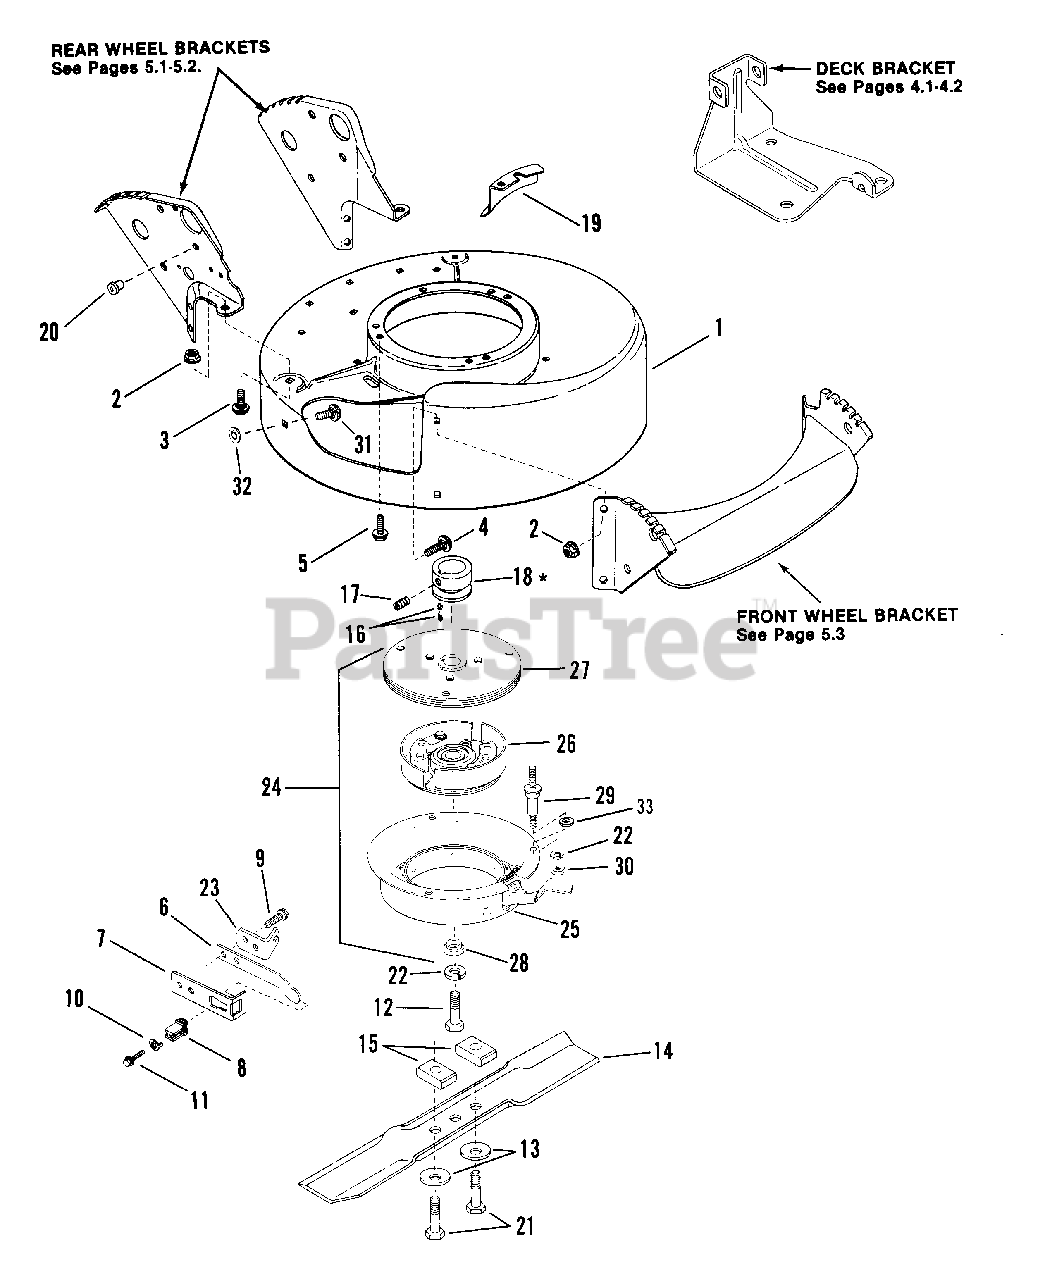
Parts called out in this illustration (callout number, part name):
1	DECK, Mower
2	NUT, Hex Flanged Lock
3	BOLT, 5/16-18 x 1/2" Short Neck Carriage Gr. 5
4	BOLT, 5/16-18 x 1" Short Neck Carriage
5	SCREW, 3/8-16 x 1" Hex Head Self-tapping (Engine Mounting)
6	SPRING, Wheel Bracket Type Interlock
7	BRACKET, Wheel Bracket Type Interlock
8	INSULATOR, Interlock
9	SCREW, 1/4-20 x 1/2" Hex Self-tapping
10	WASHER, No. 8 TAB Int. Tooth Lock
11	SCREW, No. 8-18 x 3/4" Hex Head Machine
12	SCREW, 3/8-24 x 2.0" Hex Head Cap
13	WASHER, Cone
14	BLADE, Cutter
15	SPACER, Blade
16	KEY, Hi-Pro
16	KEY, Woodruff
16	KEY, Square
17	SCREW, 5/16-18 x 5/16" Hex Socket Set
18	PULLEY, Engine (25mm I.D. x 2-1/8" O.D.)
19	SHIELD, Cover, Belt Opening
20	BUSHING, Interlock Wire
21	SCREW, 3/8-16 x 1-3/4" Hex Head Cap
22	WASHER, 3/8 Split Lock
23	BRACKET, CABLE - BBC
24	ASSEMBLY, Blade Clutch
25	ASSEMBLY, Bowl & Brake
26	ASSEMBLY, Clutch Bearing
27	ASSEMBLY, Flywheel
28	WASHER, Blade
29	STAND-OFF
30	NUT, 3/8-16 Hex Flange Lock
31	BOLT, 5/16-18 x 1" Short Neck Carriage
32	RETAINER, 5/16 Bolt
33	WASHER, 3/8" Flat
